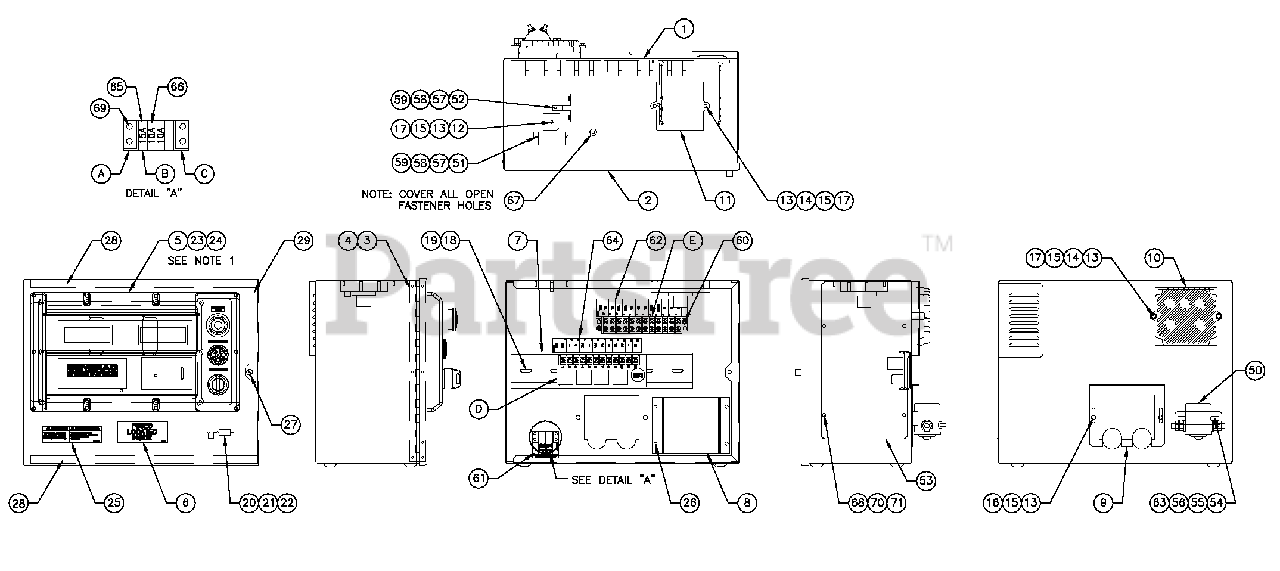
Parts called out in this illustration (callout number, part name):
1	ENCL H/G CONTROL PANEL
2	COVER CONTROL PANEL
3	HINGE CONTINUOUS H PANEL
4	RIVET POP .125 X .275 SS
5	ASSY PROGRAMMED H-100
6	DECAL FUSES LOCATED INSIDE
7	RAIL SNAPTRACK PCB HOLDER BULK (12"LG)
8	ASSY PCB 2AMP 12V UL BATT CHGR
9	PLATE HARNESS CLAMP
10	ASSY PCB PWR AVR W/AMP HEADER
11	ASSY PCB BOSCH GOV DRIVER
12	DIO BRIDGE 25A 600V
13	WASHER LOCK M5
14	SCREW PPHM M5-0.8 X 30 SS
15	WASHER FLAT M5
16	SCREW HHPM M5-0.8X 12
17	NUT HEX M5-0.8 G8 YEL CHR
18	WASHER FLAT M4
19	SCREW PHTT M4-0.7 X 10 ZYC
20	CONN DUST CAP W/CHAIN DB9
21	WASHER FLAT M3.5
22	SCREW PHTT M3.5-0.6X 10
23	SCREW PPHM M4-0.7 X 8 BLX OX
24	WASHER LOCK #8-M4
25	DECAL WRN BATT CHRG 12/24V BI
26	SCREW PHTT M4-0.7 X 12 ZYC
27	M5-0.8 CAPTIVE PANEL KNLD HD
28	SEAL COVER 3.18X12.7X382
29	SEAL COVER 3.18X12.7X283
50	RELAY CONTACTOR 12VDC
53	COVER CONTROL PANEL SIDE
54	SCREW HHC 1/4-20 X 3/4 G5
55	WASHER FLAT M6-1/4
56	WASHER LOCK M6-1/4
57	WASHER LOCK M3
58	NUT HEX M3-0.5 G8YEL CHR
59	WASHER FLAT M3
60	SCREW PHTT #6-32 X 5/8 ZYC
61	DECAL CPL CONTROL PANEL FUSES
62	DECAL CPL 5.4/6.8L TB3
63	NUT HEX 1/4-20 STEEL
64	DECAL CPL 5.4/6.8L RELAY BOARD
65	FUSE ATO TYPE 15 AMP (BLUE)
66	FUSE ATO TYPE 10 AMP (RED)
67	SEAL WEATHER .45"DIA
68	SCREW PPHM M5-0.8 X 12 ZNC
69	SCREW PHTT #6-32 X 3/8 ZYC
70	WASHER FLAT M5
71	WASHER LOCK M5
A	ADPTRRH SIDE WICKMANN 178.6191
B	HOLDER FUSE WICKMANN 178.6150
C	ADPTR LH SIDE WICKMANN 178.6192
D	ASSY PCB G-PANEL RELAY 12VDC
E	BLOCK TERM 20A12 X 6 X1100V
